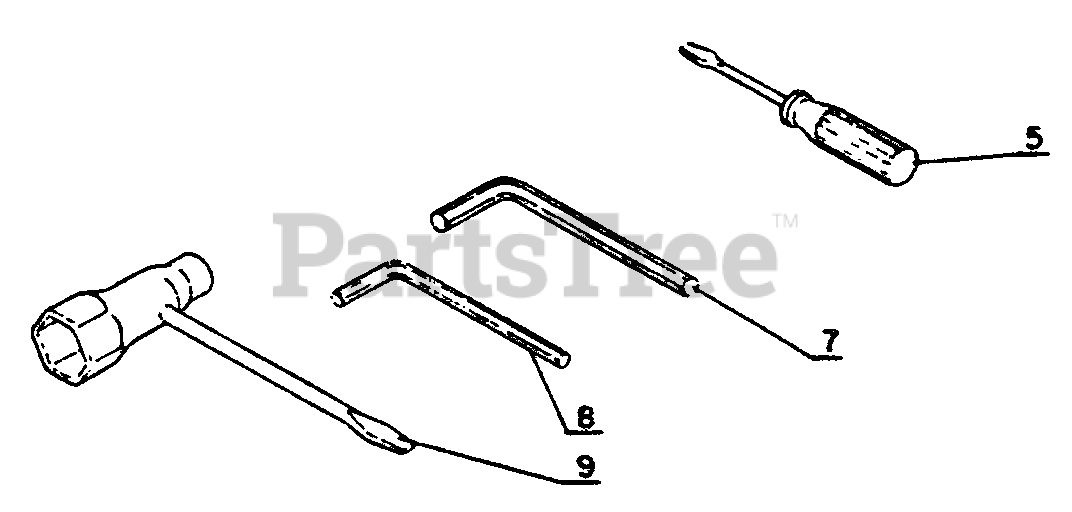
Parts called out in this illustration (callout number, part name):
5	SCREWDRIVER - 50 MM
7	WRENCH, ALLEN 4 MM
8	WRENCH, ALLEN 3 MM
9	T-WRENCH 10×19 MM
